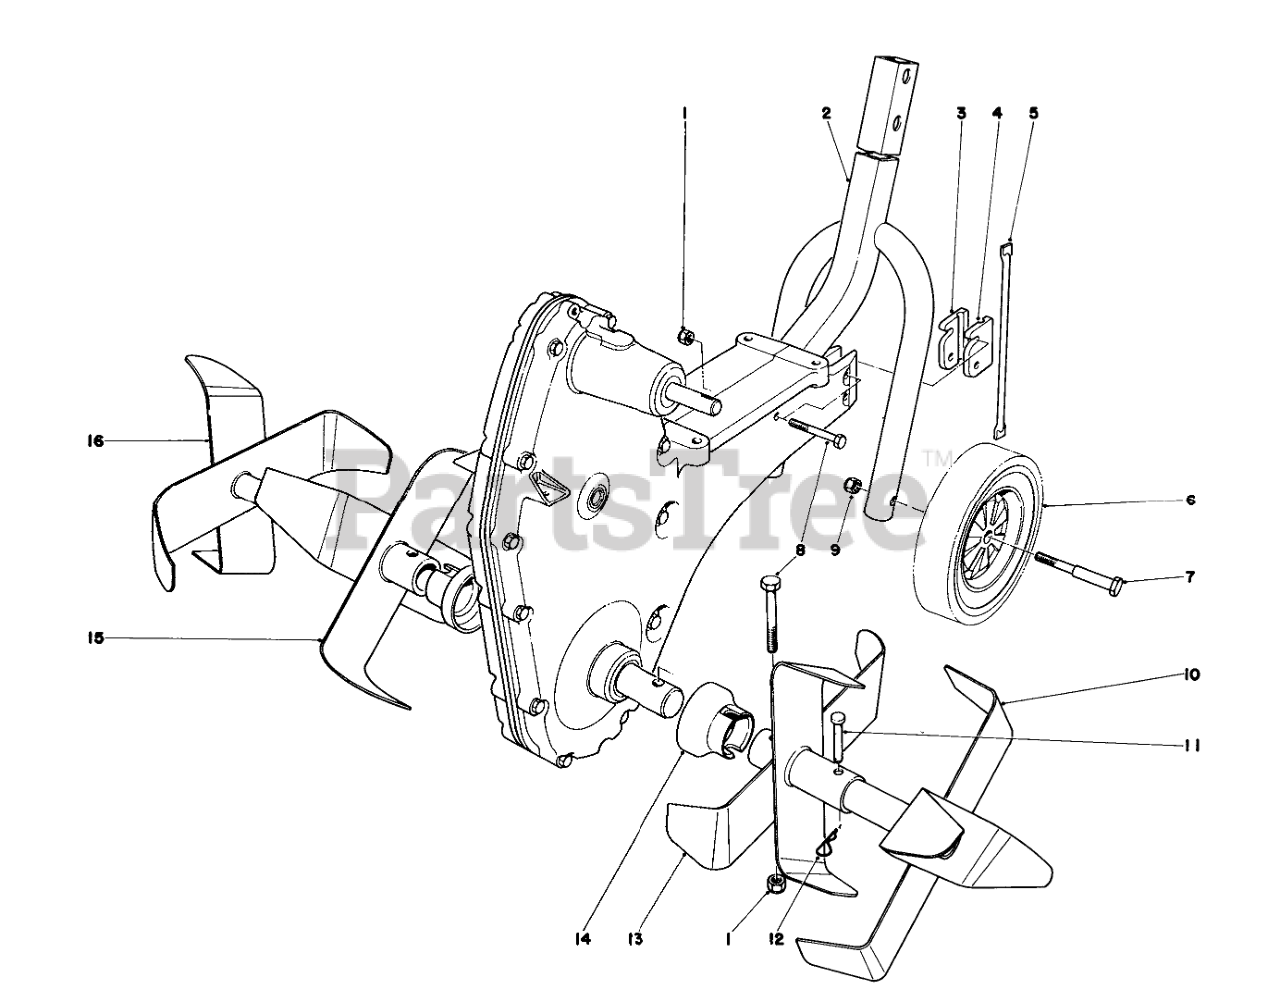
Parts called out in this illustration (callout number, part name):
1	NUT-HEX, SIDE DEFORM
2	Lower Handle
3	Pivot Block R.H.
4	Pivot Block L. H.
5	Drag Rod
6	WHEEL TIRE ASM 7 IN
7	Wheel Bolt
8	SCREW-HH
9	NUT-LOCK, CONE
10	Outboard Tine L.H.
11	CLEVIS
12	PIN-COTTER, HAIR
13	Inboard Tine L.H.
14	Dust Cover
15	Inboard Tine R.H.
16	Outboard Tine R.H.
